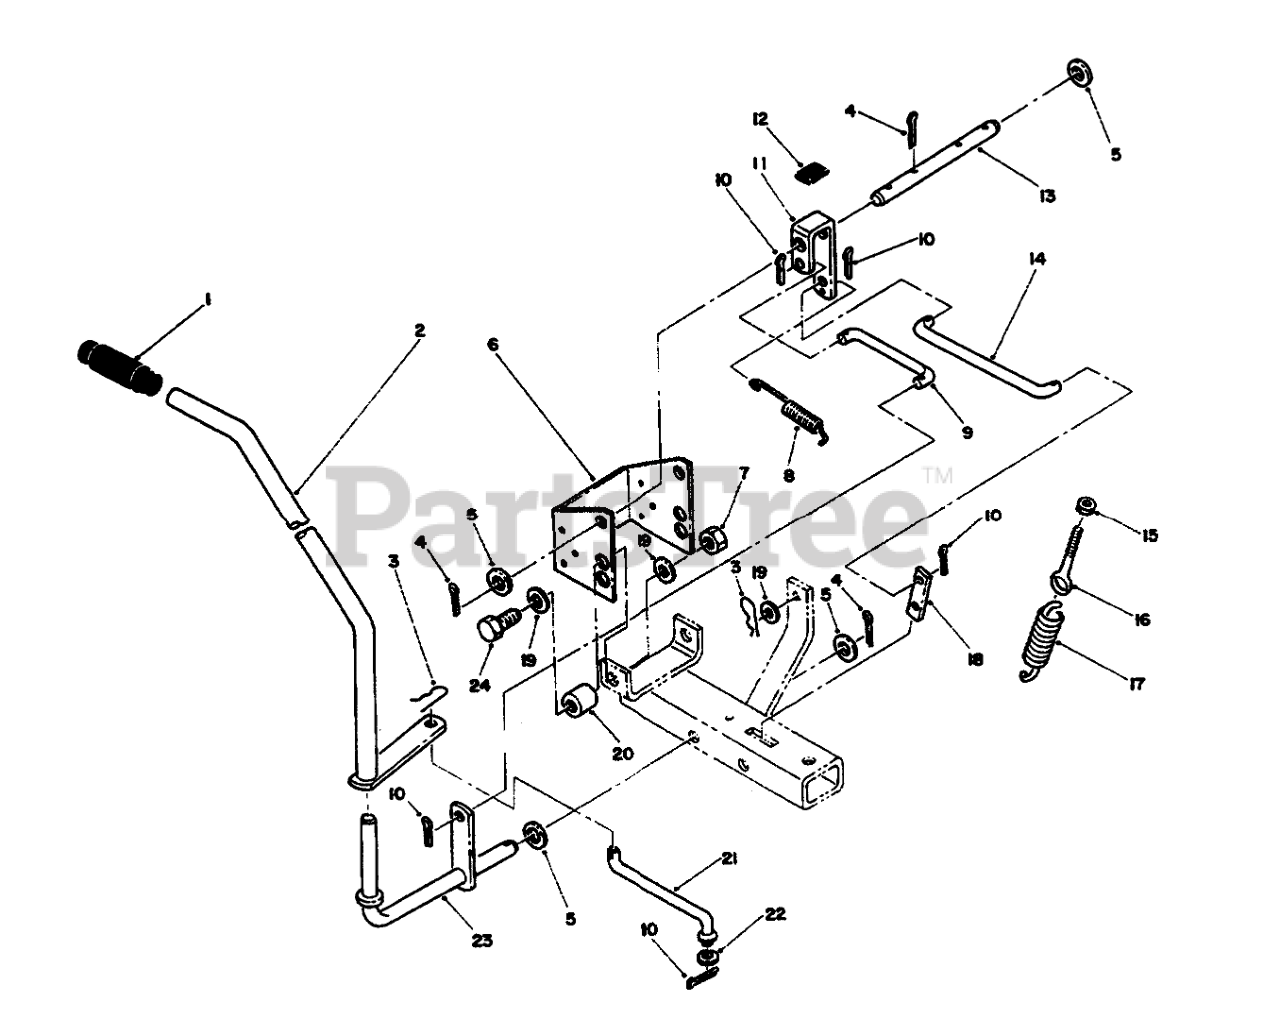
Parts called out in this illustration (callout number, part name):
1	HANDGRIP
2	ASSY-HANDLE R
3	Hairpin
4	PIN-COTTER
5	WASHER-FLAT
6	BRACKET MOUNT
7	NUT-LOCK, NI
8	SPRING
9	ROD-BELLCRANK
10	PIN-COTTER
11	BELLCRANK-LATCH R
12	RUBBER PAD
13	SHAFT R
14	ROD-LATCH
15	NUT-JAM
16	EYEBOLT
17	SPRING
18	LATCH-QUADRANT R
19	WASHER-FLAT
20	Spacer
21	ROD-ANGLING
22	WASHER-FLAT
23	ASS'Y-HANDLE PIVO R
24	SCREW-HH
